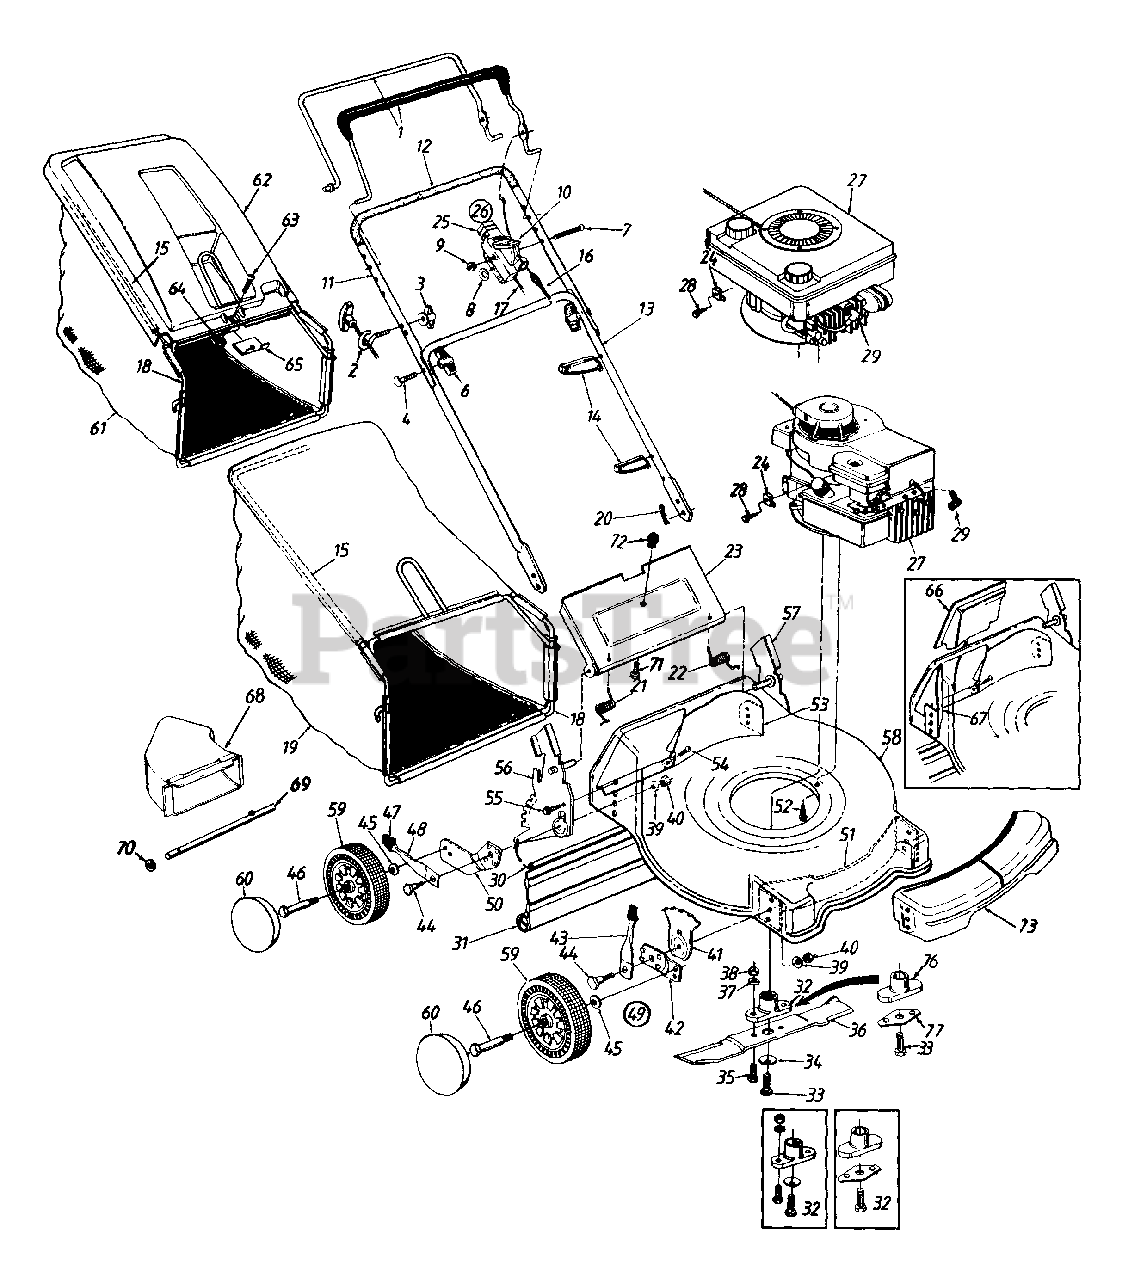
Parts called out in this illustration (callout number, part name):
2	Rope Guide
3	Handle Knob 1/4-20 Thd.
4	Curved Hd. Bolt 5/16-18 x 2" Lg.
6	Hand Knob
7	Oval C-Sunk Mach. Scr.
8	Spr. Wash. .66" I.D.
9	Hex L-Nut 1/4-20 Thd.
10	Throttle Lever
14	Cable Tie
16	Control Cable - 39"
17	Throttle Control Wire - 51"
20	Int. Cotter Pin 5/16" Dia.
21	Door Spring - R.H.
22	Door Spring - L.H.
25	Throttle Body
26	Throttle Box Comp.
27	Engine
28	Hex Wash. Hd. Scr. #10-32 x .62" Lg.
29	Spark Plug Boot
30	Wire Rod
31	Rear Flap
32	Blade Adapter Kit
33	Hex Bolt 3/8-24 x 1.5" Lg.
34	Bell-Wash. .39" I.D.
35	Hex Bolt 3/8-24 x 1" Lg.
36	21" Blade
37	L-Wash. 3/8" I.D.
38	Hex Nut 3/8-24 Thd.
39	Bell-Wash. .39" I.D. x 1.38"
40	Hex Nut 3/8-16 Thd.
41	Height Adj. Plate
43	Spring Lever Ass'y. w/Knob
44	Shld. Bolt .5" Dia. x .357"
45	Bell-Wash. .38" I.D. x .88" O.D.
46	Axle Bolt
47	Spring Lever Knob
48	Spring Lever
49	Height Adj. Ass'y. Comp. - R.H.
50	Pivot Bar
54	Torx Mach. AB-Tap Scr. 1/4 x .62" Lg.
55	Hex L-Wash. Hd. AB-Tap Scr. 1/4 x .62" Lg.
60	Hub Cap
61	Grass Bag
62	Hard Top Cover
63	Pan Hd. Mach. Scr. 1/4-20 x .5" Lg.
64	Hex Nylon L-Nut 1/4-20 Thd.
68	Deflector
69	Rod
70	Push Speed Nut
71	Truss Scr. #10-24 x .38" Lg.
73	Deck Shroud
76	Blade Adapter
77	Blade Bell Support
